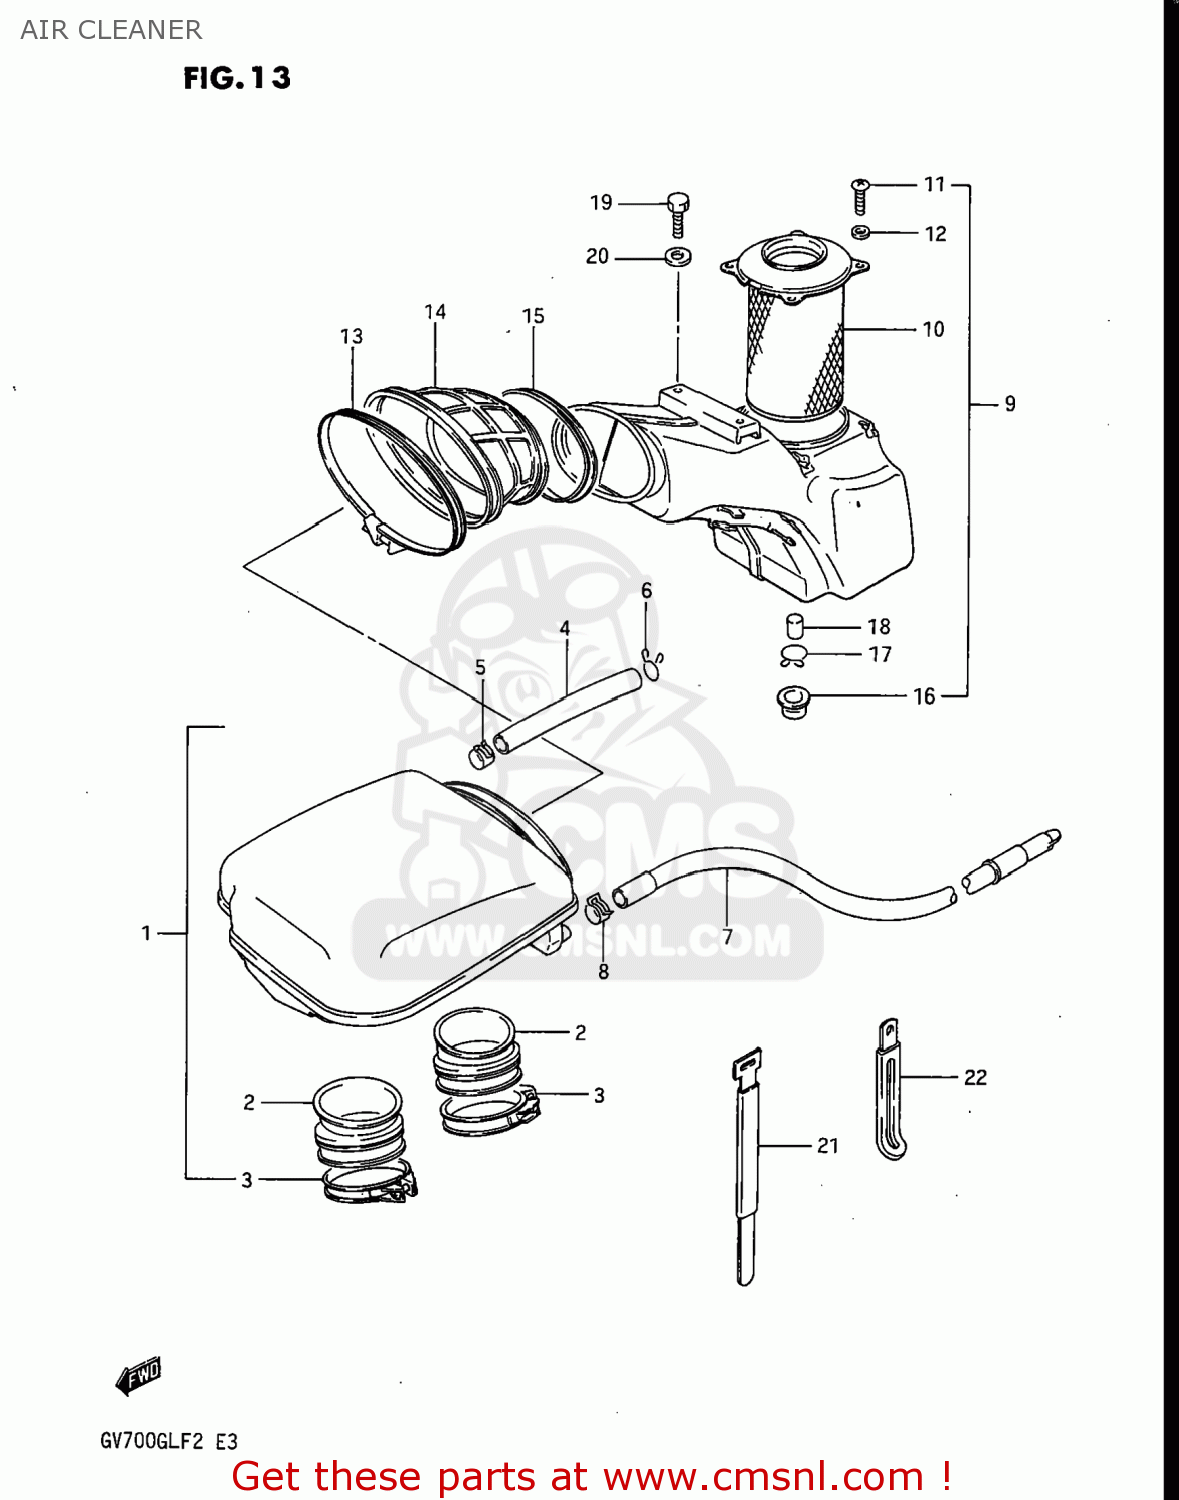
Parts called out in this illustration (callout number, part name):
1	CLEANER ASSEMBLY,AIR
2	TUBE,AIR CLEANER OUTLET
3	CLAMP
4	TUBE,BREATHER
5	CLIP
6	CLIP
7	DRAIN TUBE
8	CLIP
9	CASE ASSEMBLY,AIR CLEANER
10	FILTER,AIR CLEANER
11	SCREW
12	WASHER,LOCK
13	CLAMP
14	GUARD,MUD
15	CLAMP
16	TUBE
17	CLIP
18	FILTER,DRAIN
19	BOLT, UPPER
20	WASHER
21	CLAMP L:110
22	CLAMP
